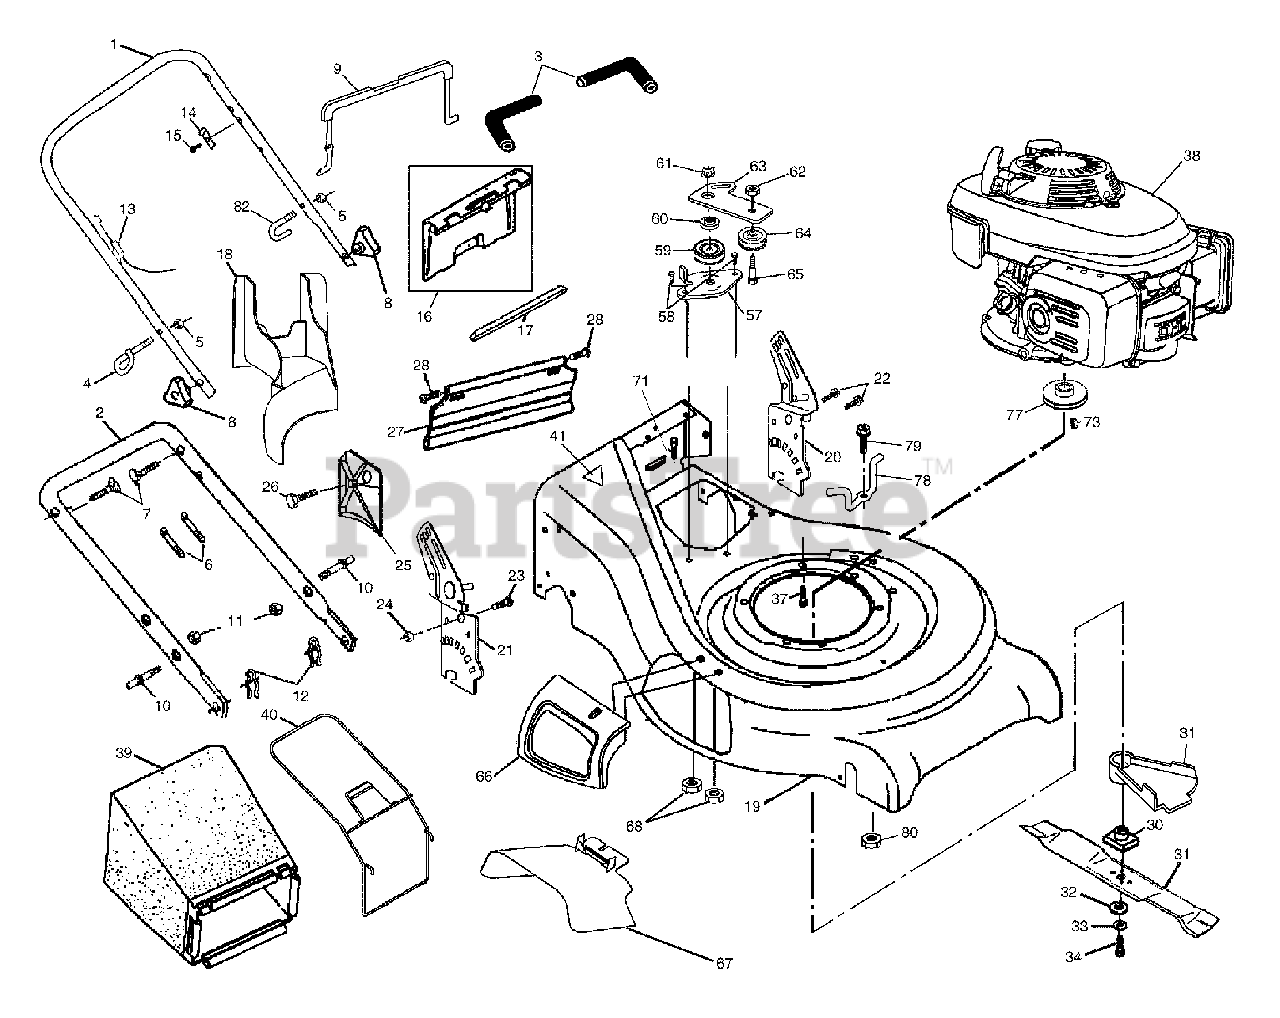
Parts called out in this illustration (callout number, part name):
1	Handle, Upper
2	Handle, Lower
3	Grip, Handle, Foam, Smooth
4	Guide, Rope, Side
5	Nut, Hex Lockwasher Insert 1/4-20
6	Wire, Tie
7	Bolt, Handle 5/16-18 x 1.75
8	Knob, Handle
9	Bail, Flat, Auto-Walk, Orange
10	Bolt, Carriage
11	Nut, Hex Lockwasher Insert 5/16-18 UNC
12	Cotter, Hairpin
13	Engine Zone Control Cable
14	Bracket, Upstop
16	Kit, Door Rear
17	Seal, Door
18	Plug, Mulcher
19	Kit, Housing
20	Handle Bracket Assembly, LH
21	Handle Bracket Assembly, RH
22	Screw, Hex Washer Head
23	Bolt, Hex Head 5/16-18 x 5/8
24	Nut, Hex, with Lock Washer Insert 5/16-18
25	Baffle, Side
26	Screw 12 x 5/8
27	Skirt
28	Screw, Hinge 1/4-20 x 1.25
30	Adapter, Blade, with Key
31	Blade, 21"
32	Washer, Hardened
33	Lockwasher, Helical Spring 3/8
34	Screw, Hex Head 3/8-24 x 1.38
37	Bolt, Engine
39	Grass Catcher Bag
40	Grass Catcher Frame
41	Danger Decal
57	Bracket Assembly
59	Pulley, V-Groove
60	Spacer, Idler Arm
61	Flange Nut
62	Locknut
63	Idler Arm
64	Idler Pulley
65	Shoulder Bolt
66	Door Assembly
67	Deflector, Door
73	Hi-Pro Key
78	Belt Keeper
81	Debris Shield
